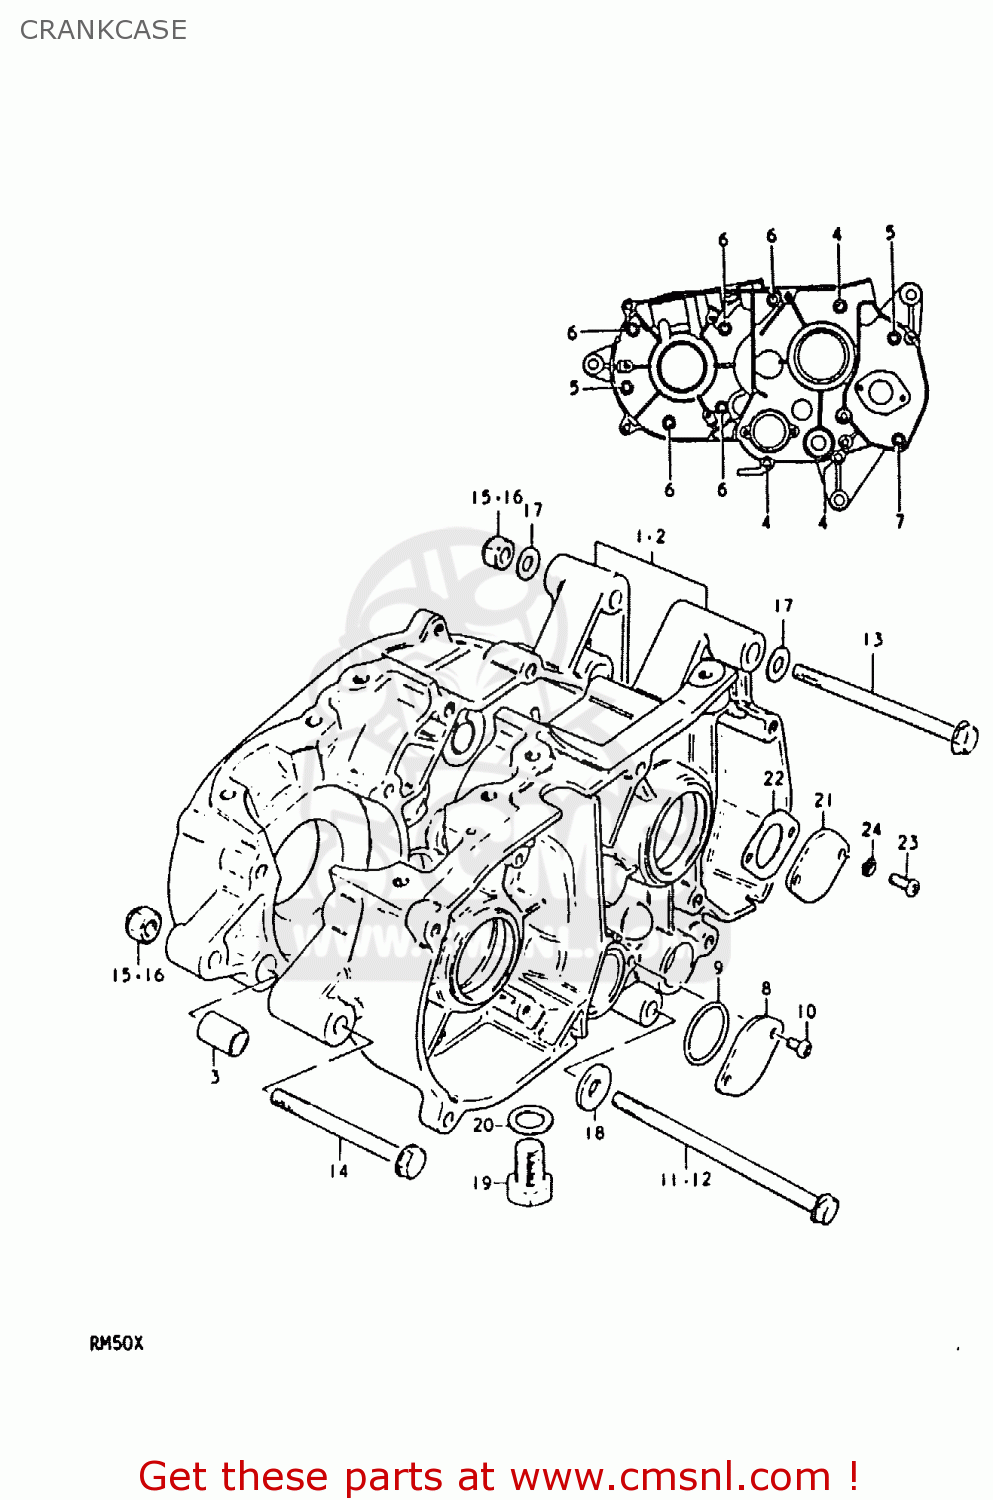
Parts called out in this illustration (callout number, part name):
1	CRANKCASE SET
2	PIN
3	SCREW
4	SCREW (6X45)
5	SCREW (6X35)
6	SCREW
7	CAP,GEAR SHIFT CAM PIVOT
8	O-RING (D:2.4 ID:26.2)
9	SCREW
10	BOLT
11	BOLT
12	BOLT
13	BOLT 8X75
14	NUT
15	NUT
16	WASHER
17	WASHER
18	BOLT 10X20
19	GASKET(10X14X3.6) (NAS)
20	CAP,OIL PUMP DRIVE SHAFT
21	GASKET,OIL PUMP (MCA)
22	SCREW
23	LOCK WASHER
